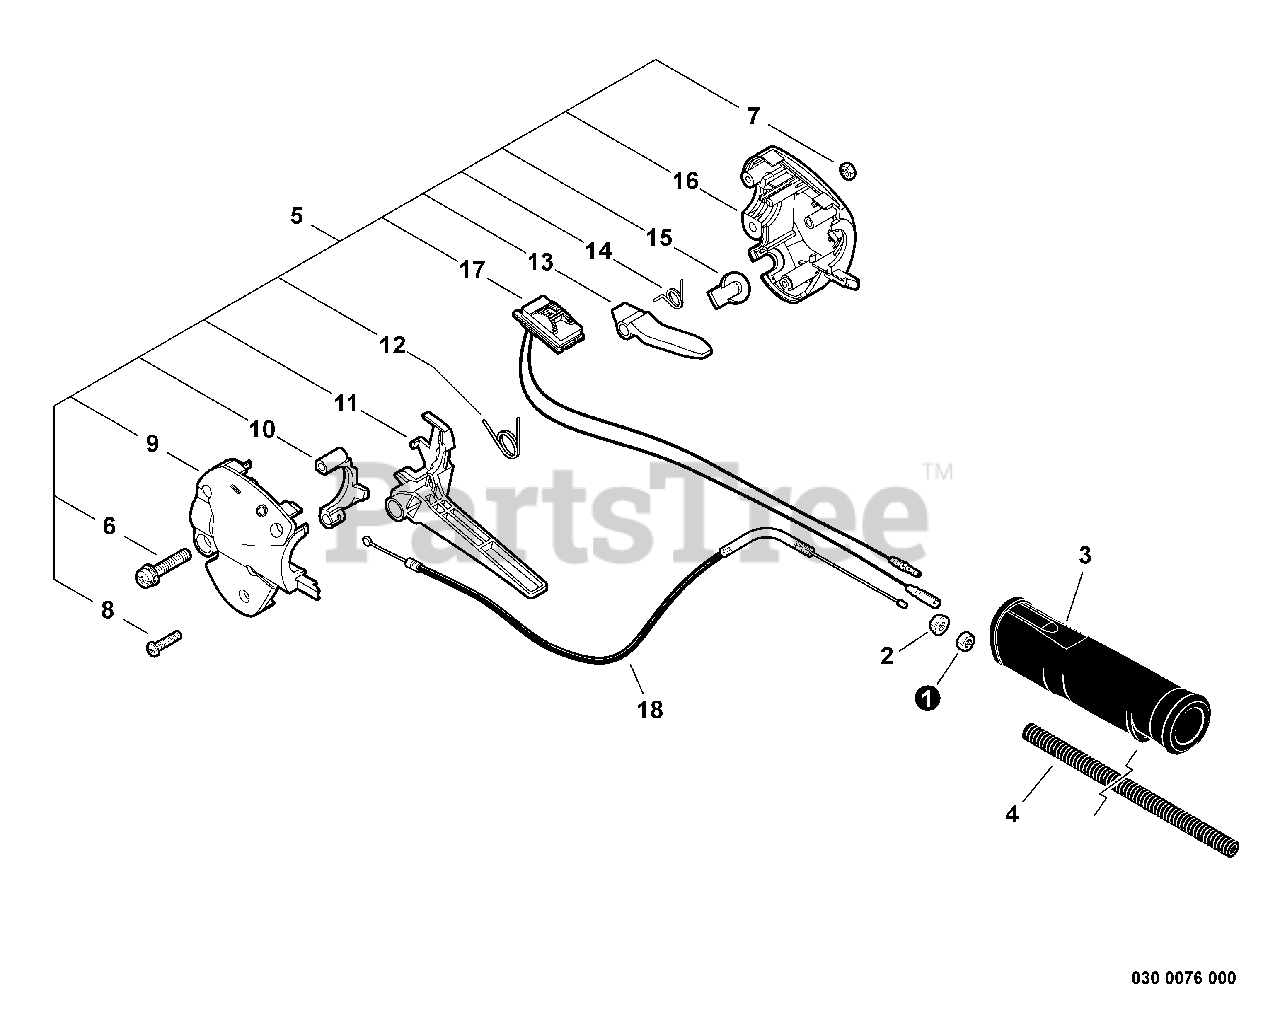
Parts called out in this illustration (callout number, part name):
2	NUT, FLANGE M6
3	GRIP, HANDLE
4	TUBE, PROTECTIVE
5	THROTTLE CONTROL ASSY
6	BOLT, TORX 5×16
7	NUT M5
9	CONTROL HANDLE - LEFT
10	LOCKOUT, THROTTLE
11	TRIGGER, THROTTLE
12	SPRING, THROTTLE RETURN
13	LEVER, THROTTLE LOCKOUT
14	SPRING, THROTTLE LOCKOUT
16	CONTROL HANDLE - RIGHT
17	SWITCH, ON-OFF
18	CABLE, THROTTLE
